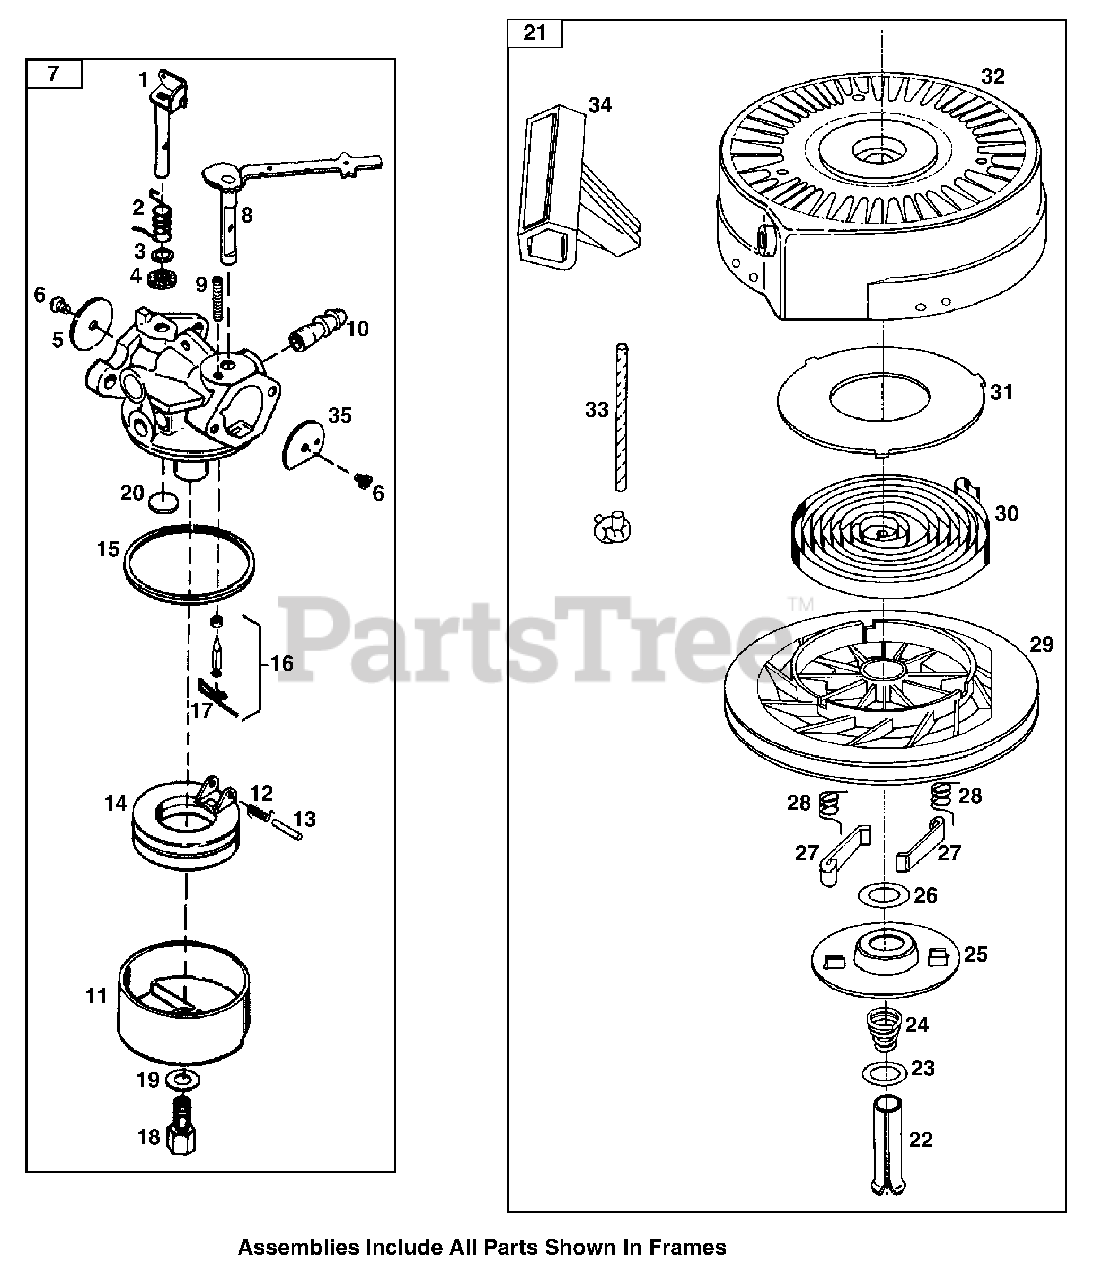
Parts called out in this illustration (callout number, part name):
1	Throttle Shaft & Lever Ass’y
2	Throttle Return Spring
3	Dust Seal Washer
5	Throttle Shutter
6	Throttle & Choke Shutter Screw
7	Carburetor Assembly
8	Choke Shaft & Lever Ass’y
9	Choke Positioning Spring
10	Fuel Fitting
11	Float Bowl
12	Float Dampening Screw
13	Float Shaft
14	Float
15	O Ring, Float Bowl & Body
16	Inlet Needle, Seat & Clip
17	Spring Clip
18	High Speed Bowl Nut
19	Bowl Nut Washer
20	Welch Plug, Atmospheric Vent
21	Rewind Starter Ass’y
22	Spring Pin
24	Brake Spring
27	Starter Dog
28	Dog Spring
29	Pulley Ass’y
30	Rewind Spring
31	Spring Cover
32	Starter Housing Ass’y
33	Starter Rope (98")
34	Starter Handle
35	Choke Shutter
